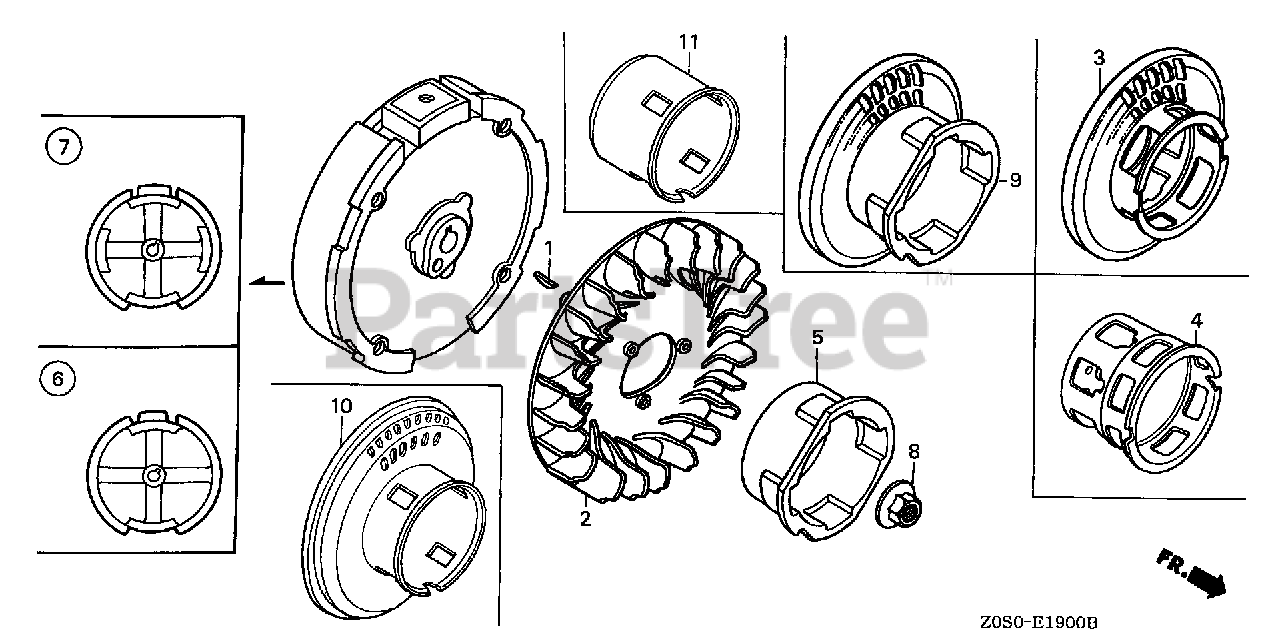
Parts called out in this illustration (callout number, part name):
1	KEY, SPECIAL WOODRUFF (25X18)
2	FAN, COOLING
5	PULLEY, STARTER
7	FLYWHEEL (LAMP)
8	NUT, SPECIAL (14MM)
11	PULLEY, STARTER
